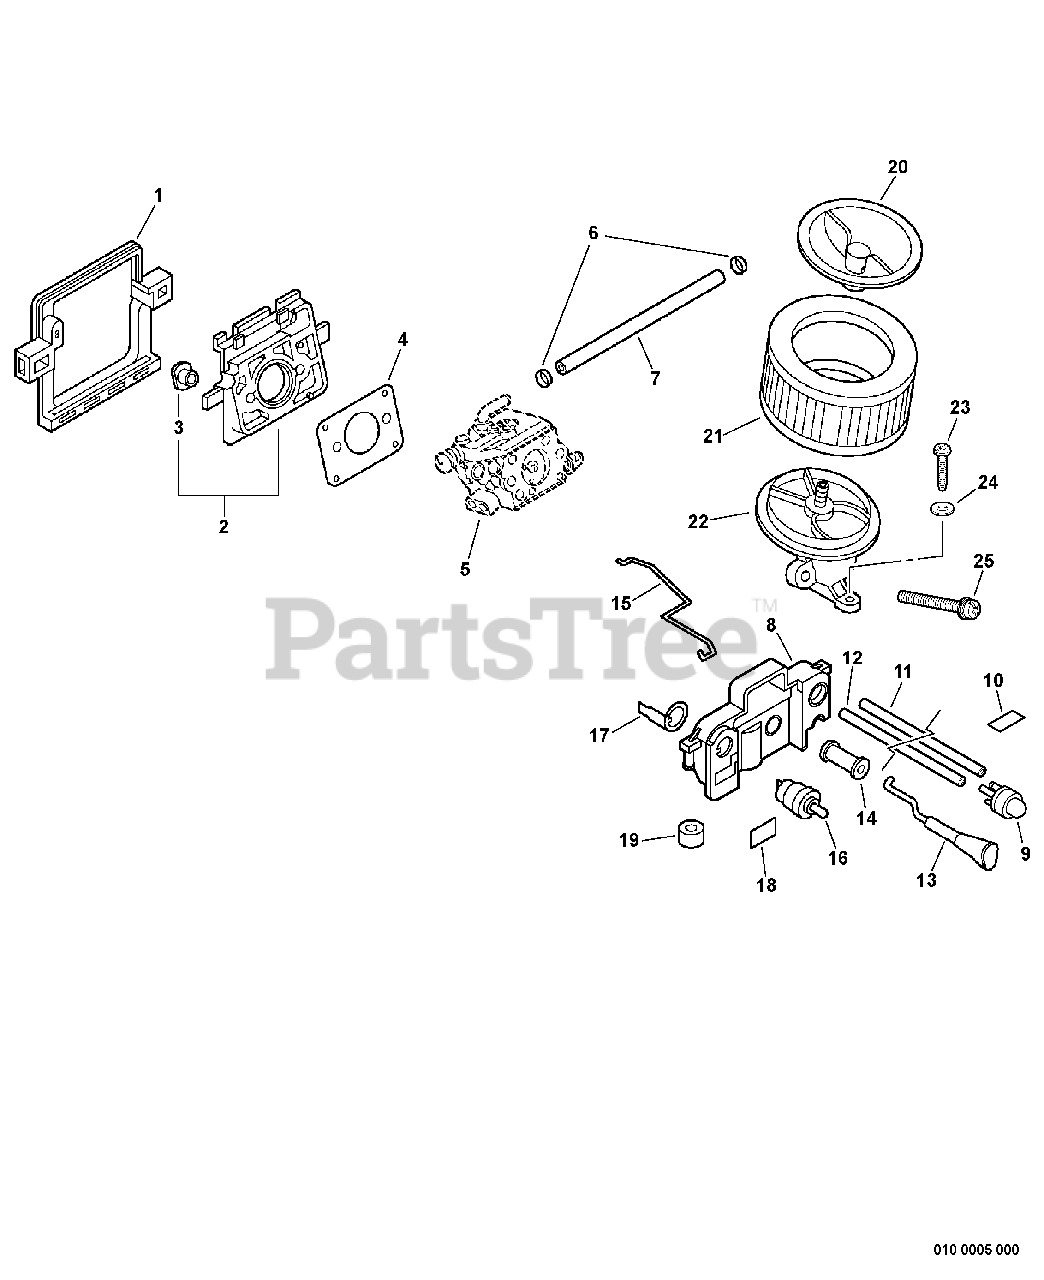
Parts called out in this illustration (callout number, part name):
1	CUSHION
2	INSULATOR KIT
4	GASKET, INTAKE
5	CARBURETOR
6	CLIP - 6
7	PIPE - 2.4X6X105 -- BLACK
8	BRACKET, SWITCH
9	PUMP, PURGE
10	LABEL - PURGE PUMP
11	PIPE - 2.4X5X200 -- BLACK
12	PIPE - 2.4X5X105 -- BLACK
13	ROD, CHOKE
14	GROMMET
15	ROD, THROTTLE
16	IGNITION SWITCH ASSY
17	TERMINAL - GROUND
18	LABEL - STOP
20	COVER, AIR FILTER
21	FILTER, AIR
22	ADAPTOR, INTAKE
23	SCREW - 5X20 -- TAPPING
24	WASHER - 5
25	SCREW - 5X45
